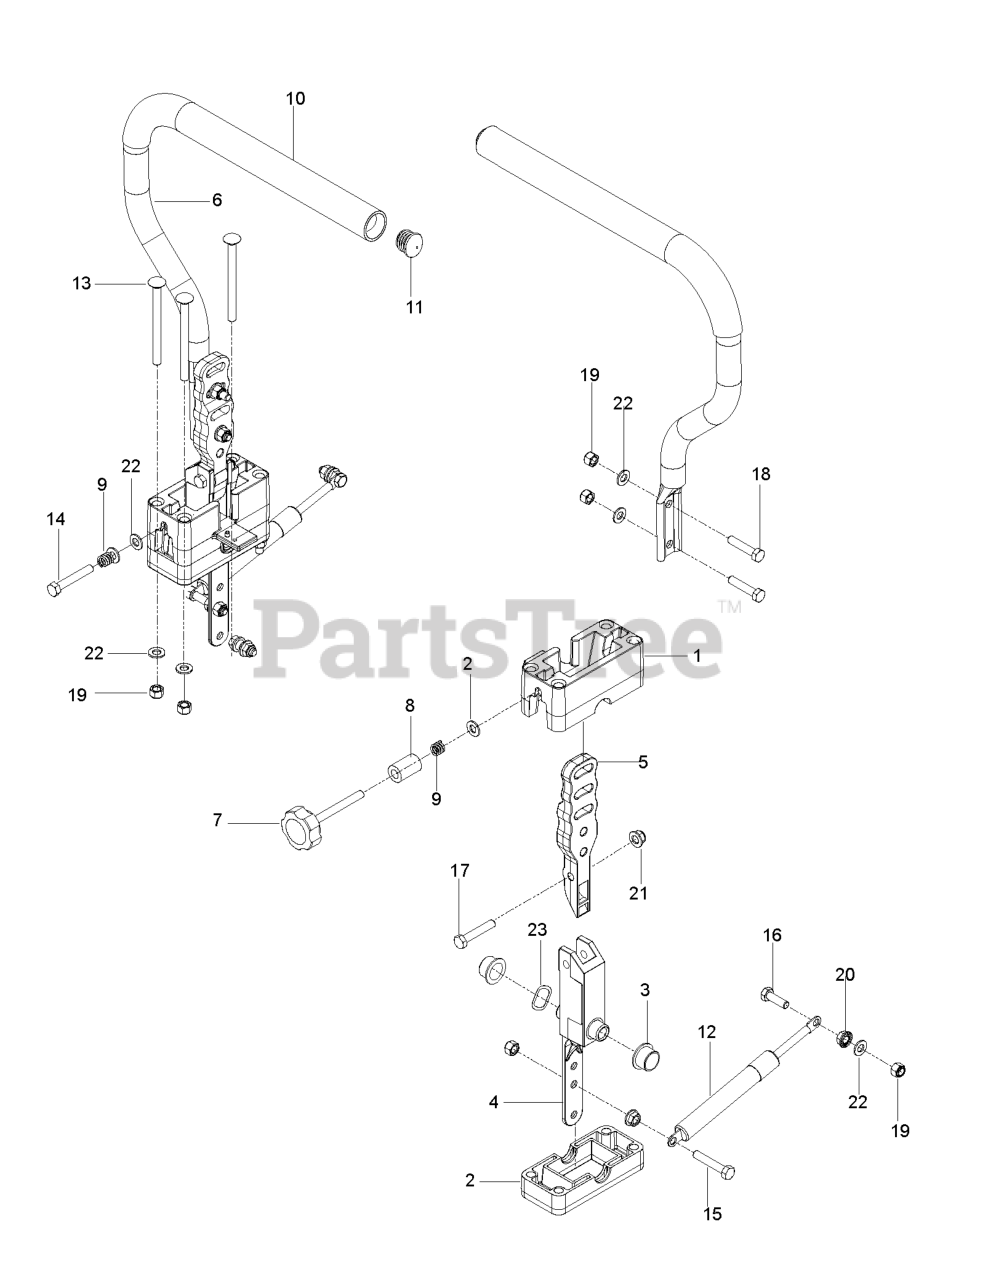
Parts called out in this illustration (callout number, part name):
1	BLOCK, UPPER
2	BLOCK, LOWER
3	BEARING, FLANGE
4	PIVOT.SECTION.DRIVE.CONTROL
5	MOUNT, DR CNTRL HANDLE
6	LEVER.DRIVE.W/GRIP
10	GRIP, FOAM (GROUND) 15
11	END PLUG 15/16 (BLACK)
13	RHSNB 5/16-18 X 4 GR 5 ZD
14	HCS 5/16-18 X 2 TPBLT GR 5 ZD
15	HCS 5/16-18X1-3/4 TPBLT
16	HCS 5/16C X 1
17	HCS 5/16C X 1 3/4
18	CAPSCREW 5/16 X 1/1/2 HEX HEAD
19	NUT 5/16 NYLOC
20	NUT 5/16C WHIZ
21	5/16-18 NYLOC FLANGE NUT
22	FLAT WASHER 5/16 SAE
23	WASHER, .825 X 1.087, WAVE
